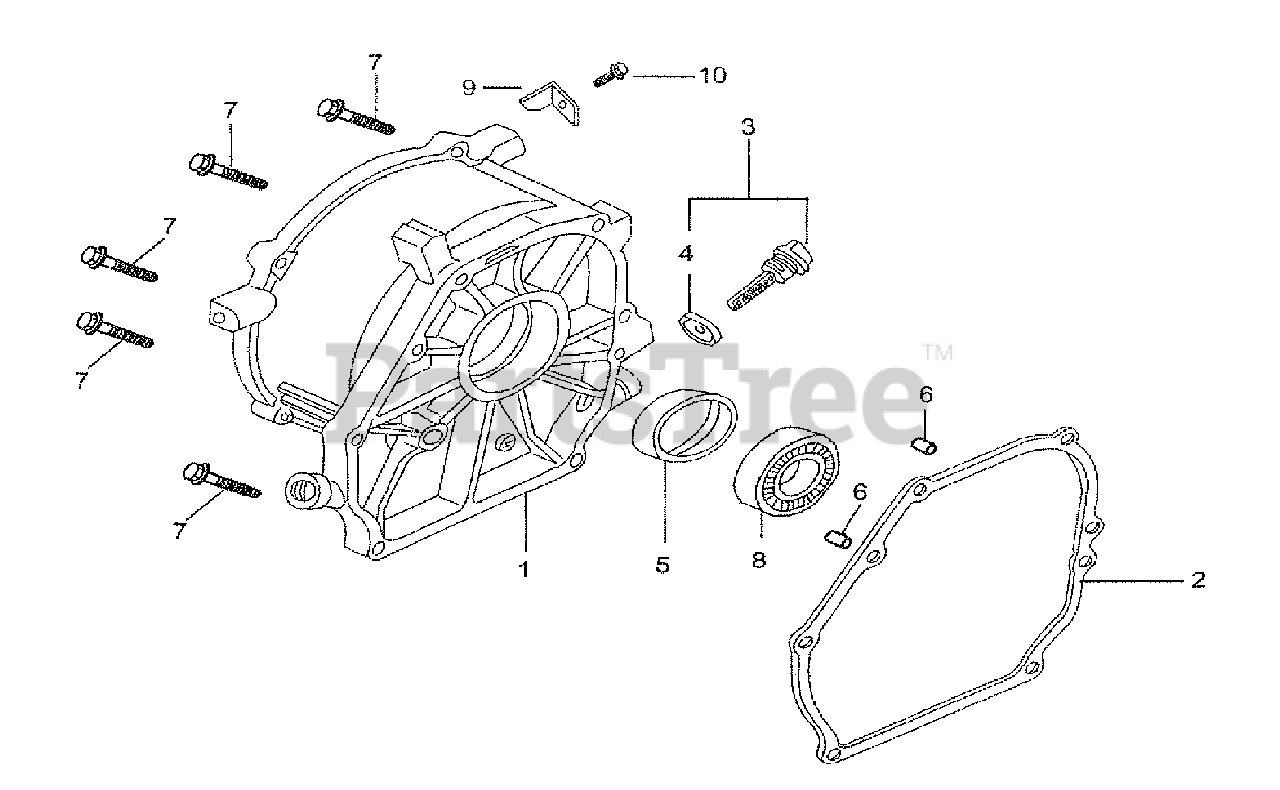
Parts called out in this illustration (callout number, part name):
1	COVER ASSY., CRANKCASE
2	GASKET,CASE COVER
3	CAP ASSY.,OIL FILLER(YELLOW)
4	GASKET, OIL FILLER CAP
5	OIL SEAL 25X41.25X6
6	DOWEL PIN 8X14
7	BOLT, FLANGE 8X32
8	BEARING, BALL RADIAL 6205
9	DUST PLATE
10	BOLT, FLANGE 6X12
